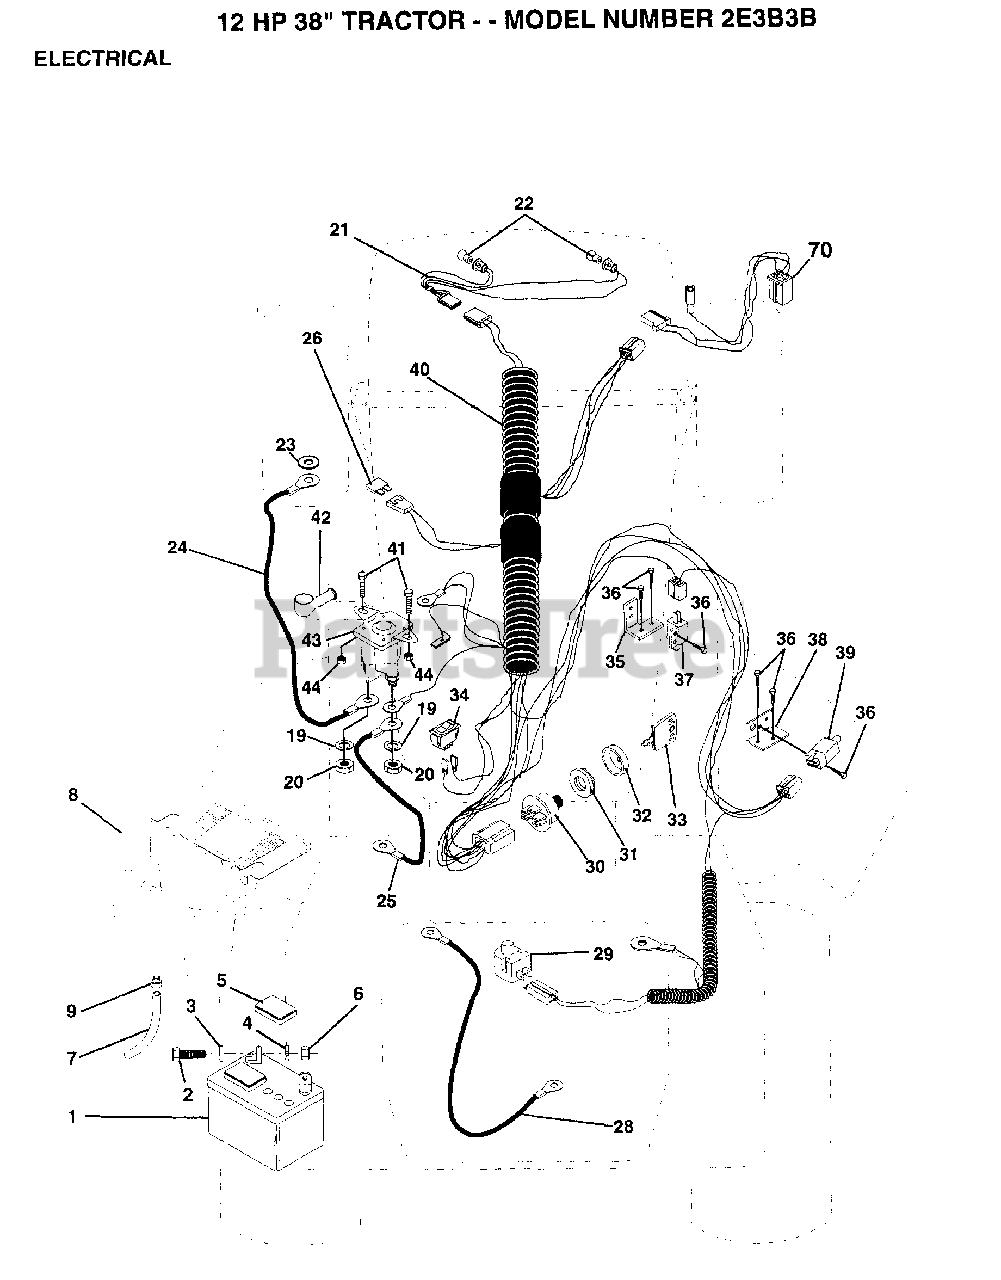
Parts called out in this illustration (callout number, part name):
2	BOLT LT
3	WASHER
4	LOCKWASHER
5	"CAP,BATTERY "
7	TUBE T
9	HOSE CLAMP T
20	NUT
21	"HARNESS,LIGHT SOC"
22	HEADLAMP BULB
23	LOCKWASHER
24	"CABLE T, BATTERY"
26	FUSE HYT
28	CABLE T
29	SWITCH SEAT
32	COVER KEY SWITCH
33	KEY MLD GEN DELTA
34	SWITCH LT
35	BRACKET LT
36	SCREW
37	SWITCH-INTER. GT
38	BRACKET SWITCH IN
39	SWITCH INTERLOCKT
40	HARNESS IGN DASH
41	BOLT HXHD FIN
44	NUT HXKEP 1/4X20
70	HARNESS ENG DUAL
